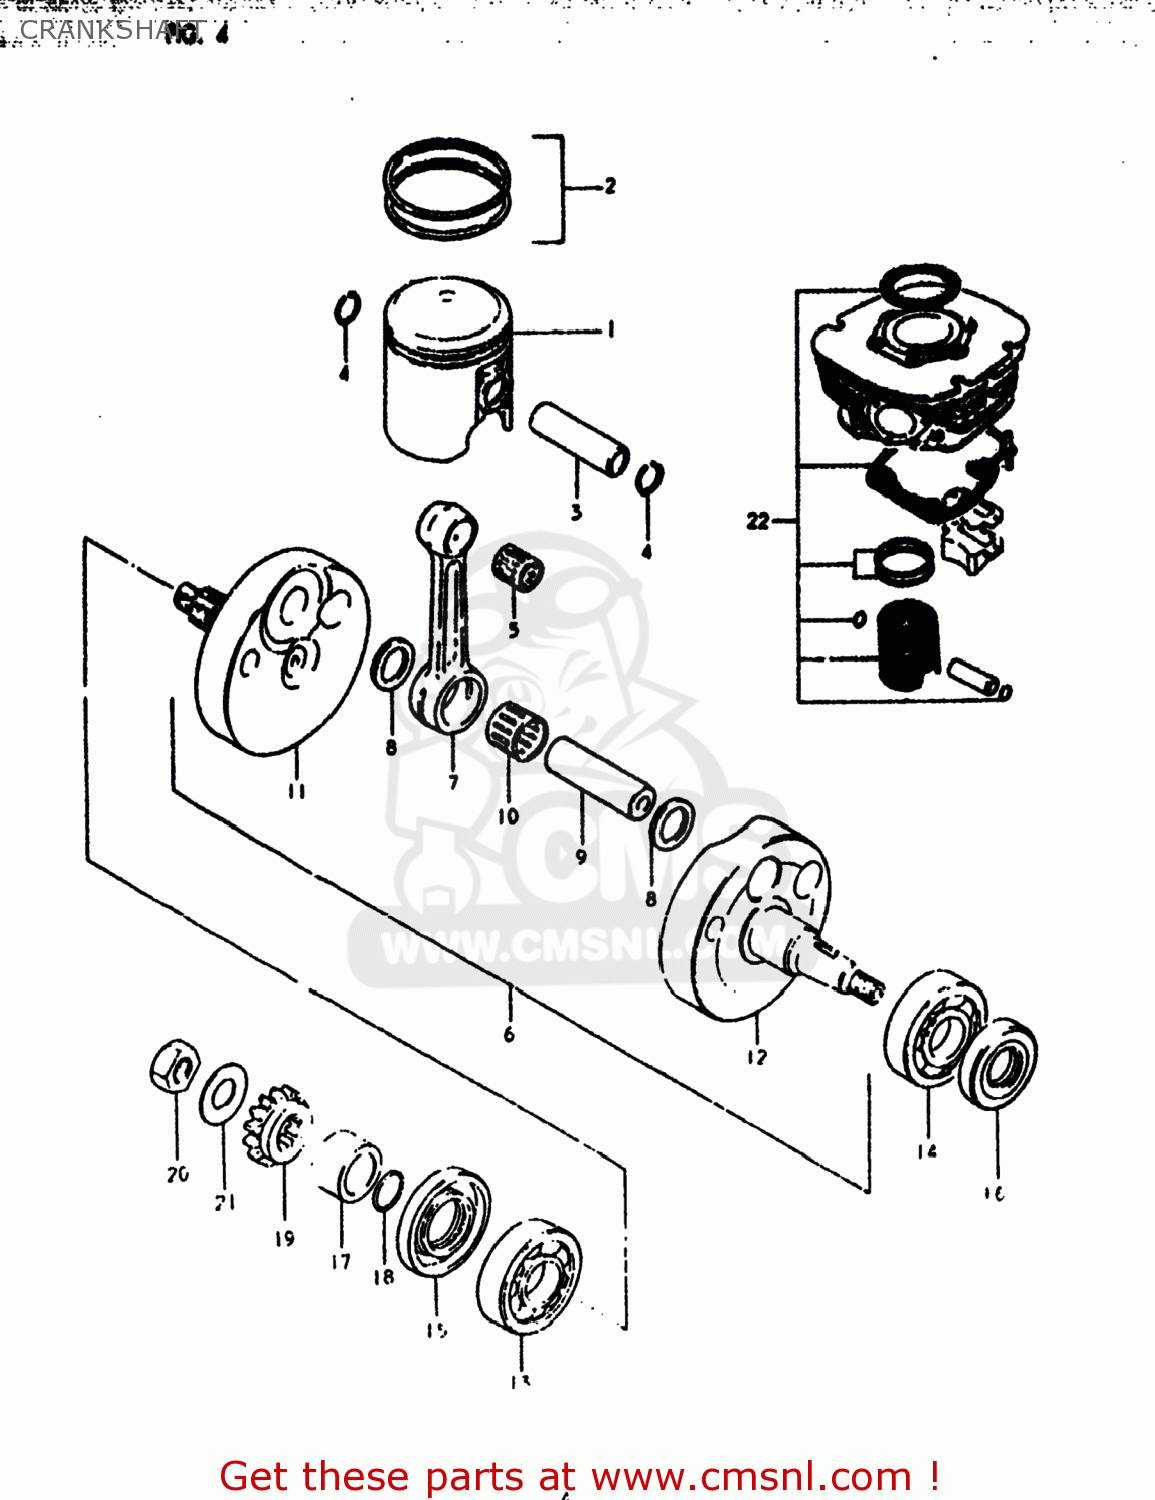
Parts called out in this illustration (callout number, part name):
1	PISTON
2	RING SET,PISTON
3	PIN,PISTON
4	RING,SNAP 14MM
5	BEARING
6	CRANKSHAFT ASSEMBLY
7	CONNECTING ROD
8	WASHER(19X32X1)
9	PIN,CRANK
10	BEARING(19X25X16)
11	CRANKSHAFT
12	CRANKSHAFT,LEFT
13	BEARING
14	BEARING
15	SEAL,OIL(29X47X8)
16	OIL SEAL
17	SPACER (20X29X20.5)
18	O RING(D:2.4,ID:19.8)
19	GEAR,PRIMARY DRIVE
20	NUT
21	WASHER
22	PISTON SET
